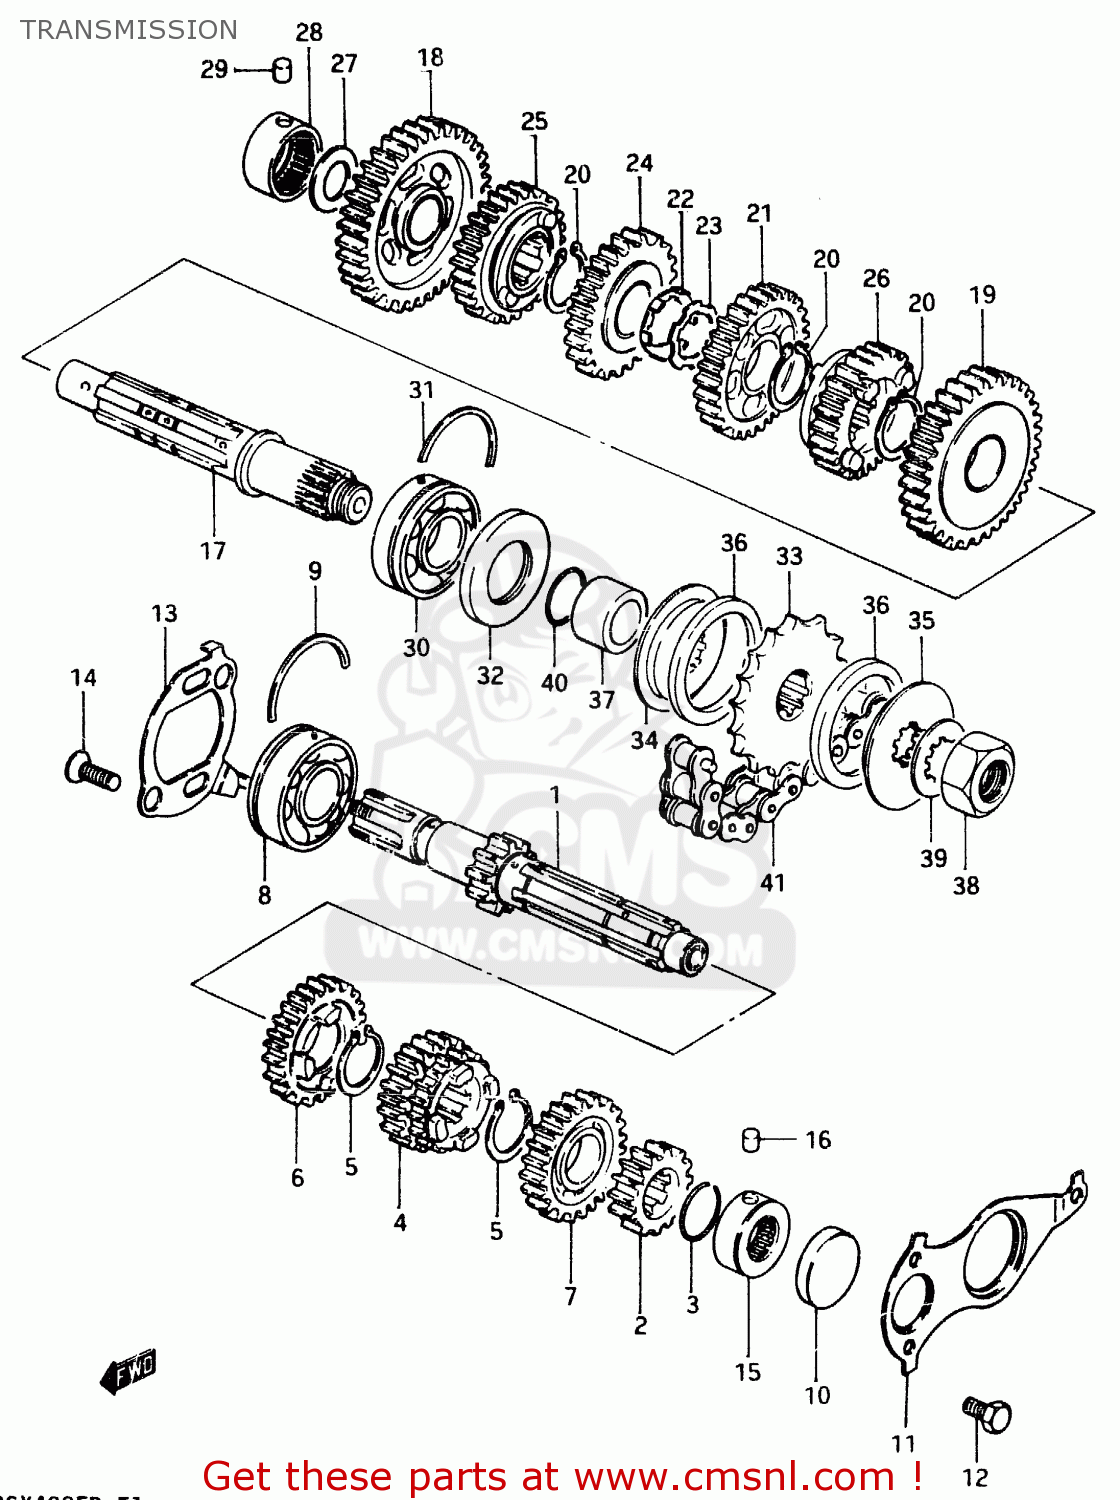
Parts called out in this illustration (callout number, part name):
1	COUNTERSHAFT ASSY
2	GEAR, 2ND DRIVE (NT:16)
3	CIRCLIP
4	GEAR, 3/4 DRIVE (NT:19/21)
5	CIRCLIP
6	GEAR, 5TH DRIVE (NT:23)
7	GEAR, 6TH DRIVE (NT:24)
8	BEARING, RH
9	C RING
10	PLUG
11	HOLDER
12	BOLT
13	HOLDER, BEARING
14	SCREW
15	BEARING, LH
16	PIN
17	DRIVESHAFT
18	GEAR, 1ST DRIVEN (NT:38)
19	GEAR, 2ND DRIVEN (NT:34)
20	CIRCLIP
21	GEAR, 3RD DRIVEN (NT:31)
22	WASHER
23	WASHER,LOCK
24	GEAR, 4TH DRIVEN (NT:28)
25	GEAR, 5TH DRIVEN (NT:27)
26	GEAR, 6TH DRIVEN (NT:26)
27	WASHER,THRUST
28	BEARING(20X34X20)
29	PIN
30	BEARING
31	C RING
32	OIL SEAL 30X56
33	SPROCKET,ENGINE
34	HOLDER, RH
35	HOLDER, LH
36	DAMPER,ENGINE SPROCKET
37	SPACER
38	NUT
39	WASHER,LOCK
40	O RING(D:1.7,ID:22)
41	CHAIN ASSEMBLY,DRIVE
